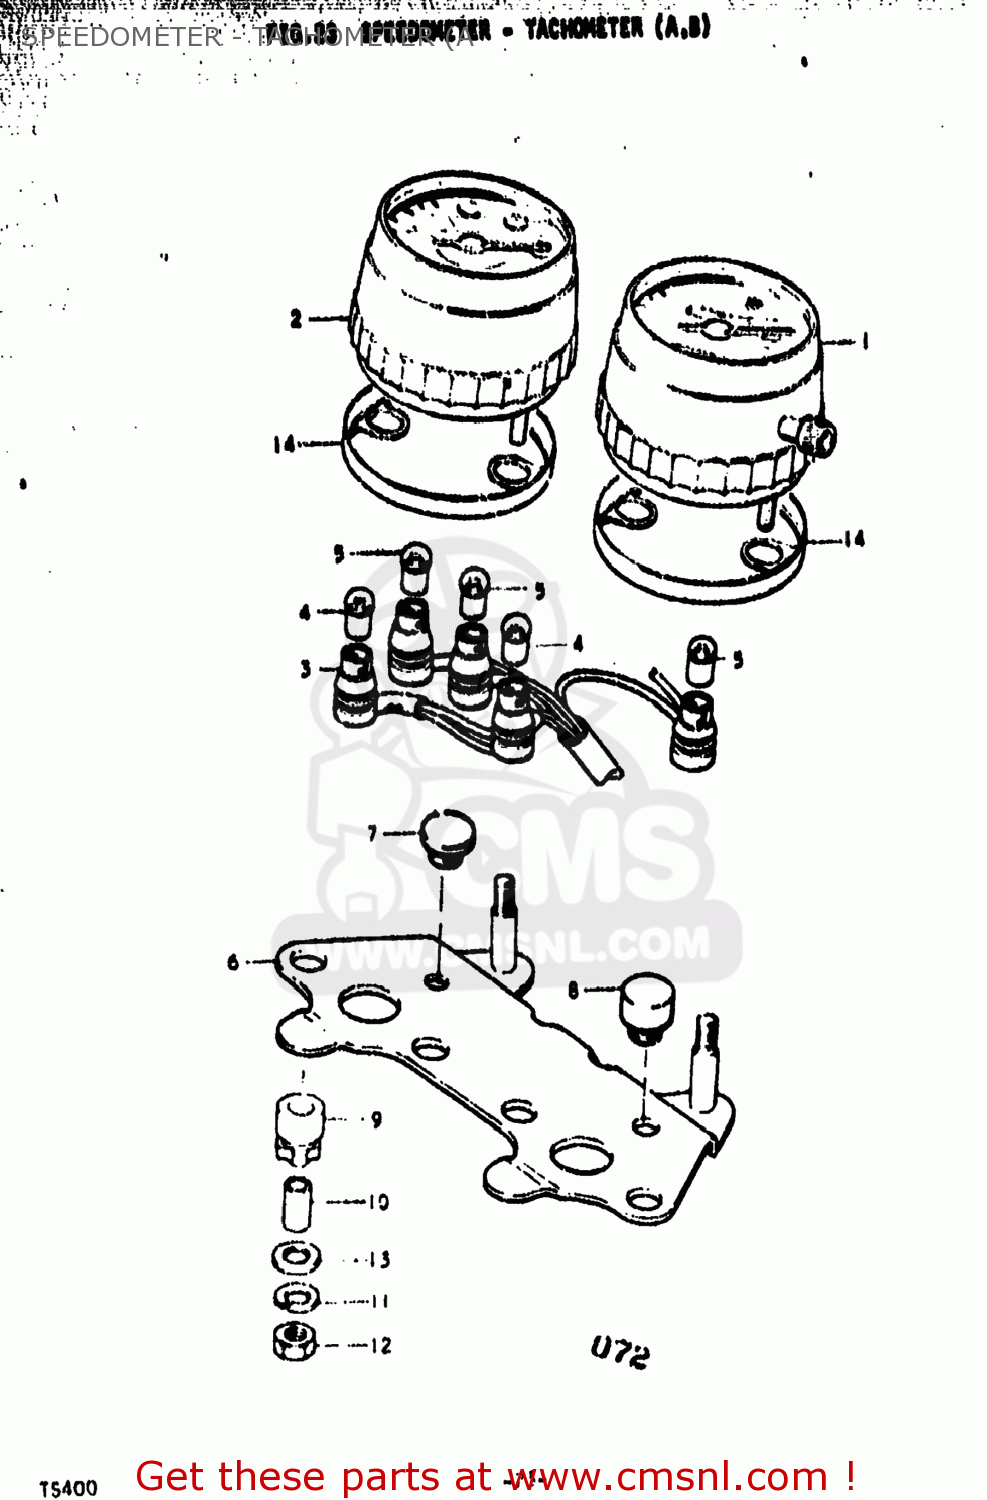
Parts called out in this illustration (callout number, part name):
0	SPEEDOMETER ASSEMBLY
1	SPEEDOMETER ASSEMBLY
2	TACHOMETER
3	SOCKET,METER
4	BULB(6V1.7W,STANLEY,A61A)
5	BULB(6V/3W)
6	BRACKET,METER
7	CUSHION,METER
8	CUSHION,METER
9	CUSHION,METER NO.1
10	SPACER,METER
11	LOCK WASHER
12	NUT
13	WASHER
14	BRACKET,SPEEDOMETER
